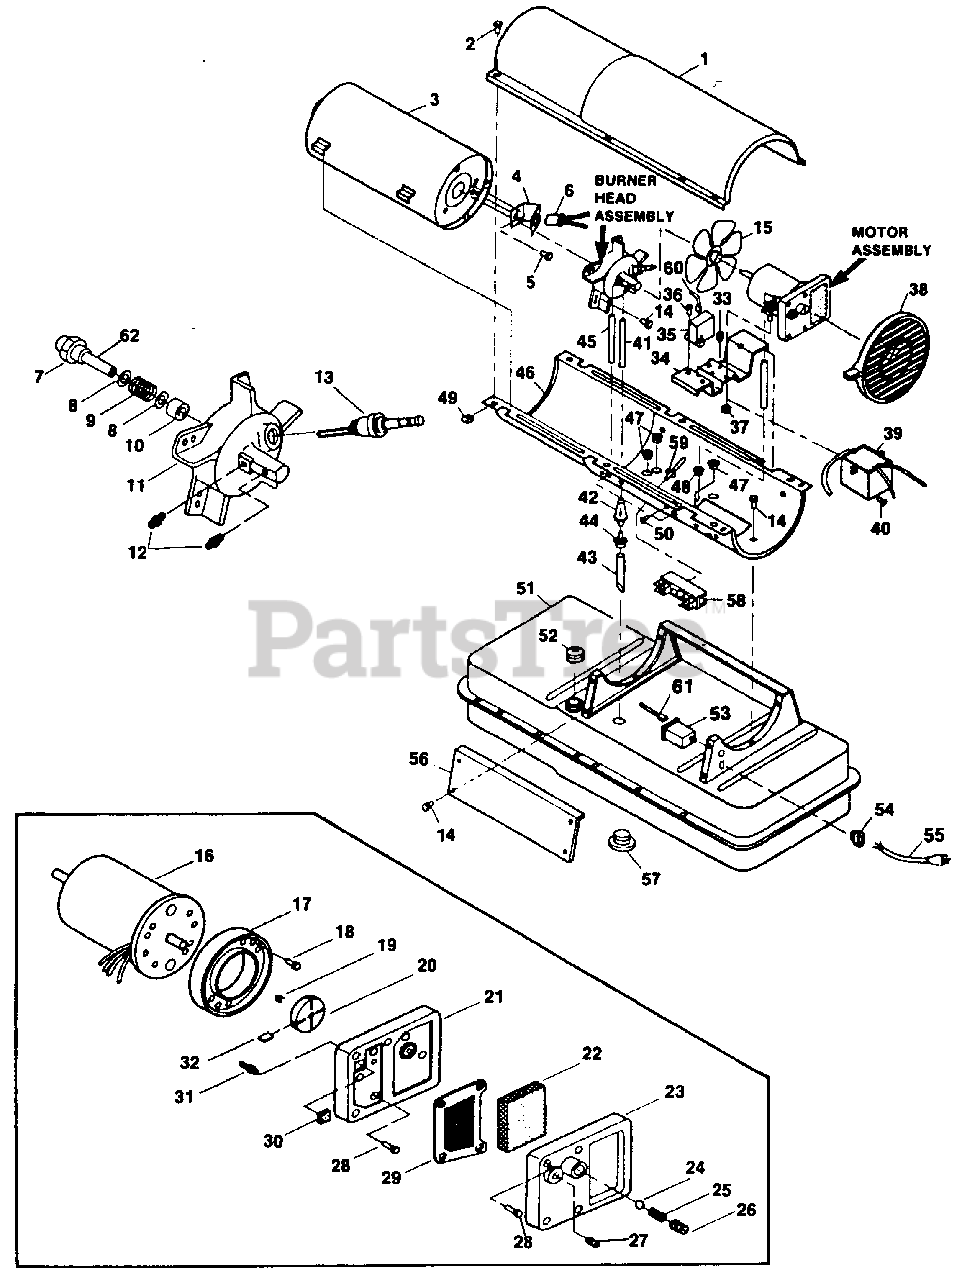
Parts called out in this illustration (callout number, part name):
1	SHELL- Upper
2	SCREW- (#10-16 x 1/2")
3	COMBUSTION CHAMBER KIT
4	BRACKET- Photocell
5	SCREW- (#6-32 x 3/8")
6	PHOTOCELL
8	NOZZLE WASHER (5")
9	SPRING- Nozzle (5")
10	SLEEVE- Nozzle (5")
11	BODY- Burner head
12	FITTING- Barb
13	SPARK PLUG
14	SCREW- Hex (#10-16 x 1/2")
16	MOTOR (Split Phase)
17	BODY- Pump (35")
18	SCREW- (#10-32 x 1/2")
19	INSERT- Rotor (10")
20	ROTOR- Pump (8")
21	COVER- Pump end (8")
22	FILTER- Intake (10")
23	COVER- Filter end (5")
24	BALL- Steel (1/4" dia)
25	SPRING- Relief
26	SCREW- Adjusting
28	SCREW- (#10-32 x 1")
29	FILTER- Output (10")
30	FILTER- Lint
31	FITTING- Barb
32	BLADE- (20")
33	BUMPER- Rubber
34	BRACKET- Motor mtg.
35	RELAY- Solid State
36	SCREW (#8-15 x 1/2")
37	NUT- Hex (1/4-20)
38	GUARD- Fan
39	IGNITOR KIT
40	SCREW (#10-16 x 3/4")
41	LINE- Fuel
42	FILTER- Fuel (2")
43	TUBE- Fuel line
44	BUSHING- Rubber
45	AIR LINE TUBE
46	SHELL- Lower
49	NUT- Tinnerman
50	SCREW- (#8-18 x 1/4")
51	TANK- Fuel
52	CAP- Fuel (Incl. gasket)
53	SAFETY CONTROL
54	BUSHING- Strain relief
55	POWER CORD
56	COVER- Side
57	PLUG- Drain (Inc. "O" ring)
58	BOARD- Terminal
59	RIVET (3/16")
60	WIRING ASSEMBLY (Red, 14 1/2")
61	WIRING ASSEMBLY (Red, 6")
